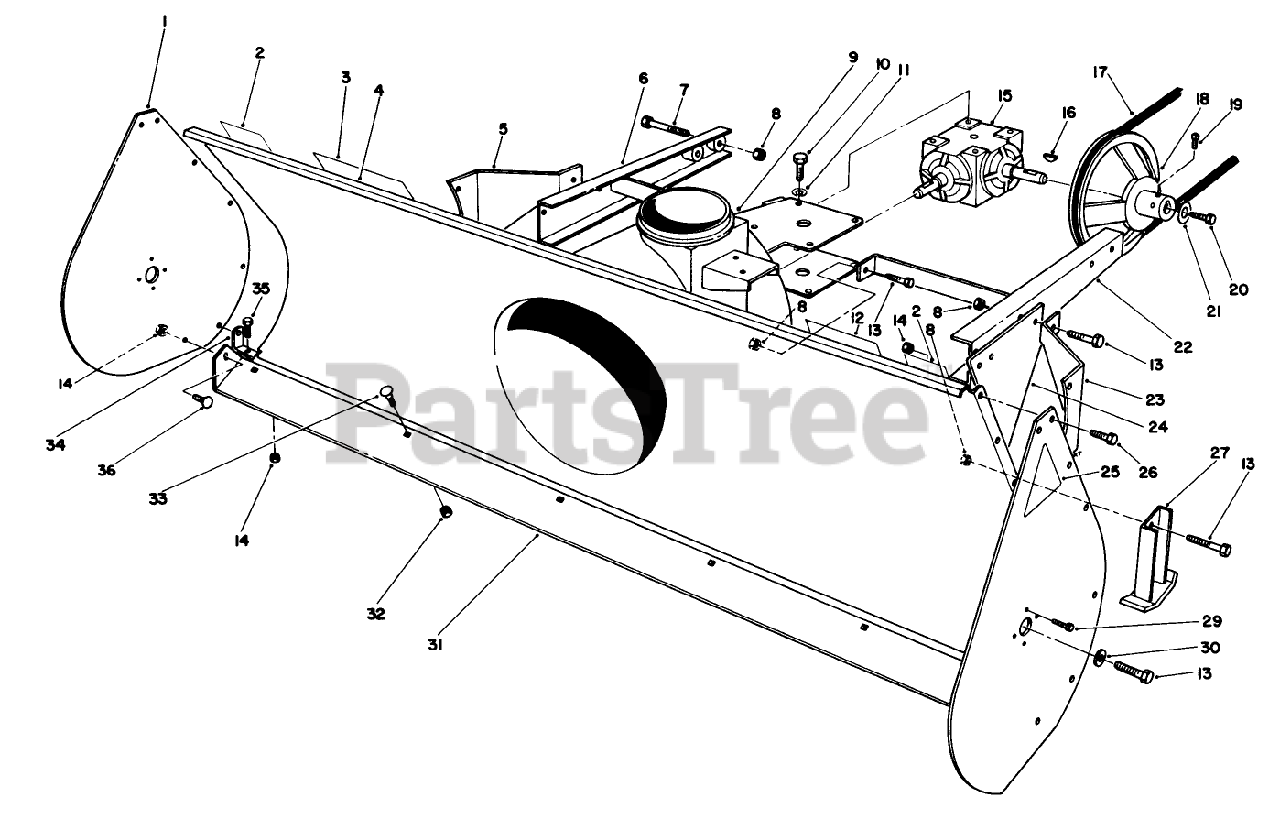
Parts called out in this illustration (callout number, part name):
1	Plate-Side
2	DECAL-WARNING, AUGER
3	Decal-Warning
4	HOUSING WA R
5	RH EXTENSION PLT R
6	RH EXT BAR WA R
7	SCREW-HH
8	NUT-LOCK, NI
9	CHUTE RING
10	SCREW-HH
11	WASHER-LOCK, INTERNAL
12	Decal-Rear Weight
13	SCREW-HH
14	NUT-LOCK, NI
15	GEARBOX
16	KEY-WOODRUFF
17	V-BELT
18	DRIVE PULLEY
19	SCREW-SET, SQH
20	BOLT 60183
21	WASHER-FLAT
22	LH EXT BAR WA R
23	LH EXTENSION PLT R
24	SKID MTG PLT R
25	AUGER SIDE PLT DECAL
26	SCREW-HH
27	SKID WA R
29	SCREW-HH
30	WASHER
31	Blade-Scraper
32	NUT-LOCK, NI
33	SCREW-CARR
34	BLADE SUPPORT BRKT R
35	SCREW-HH
